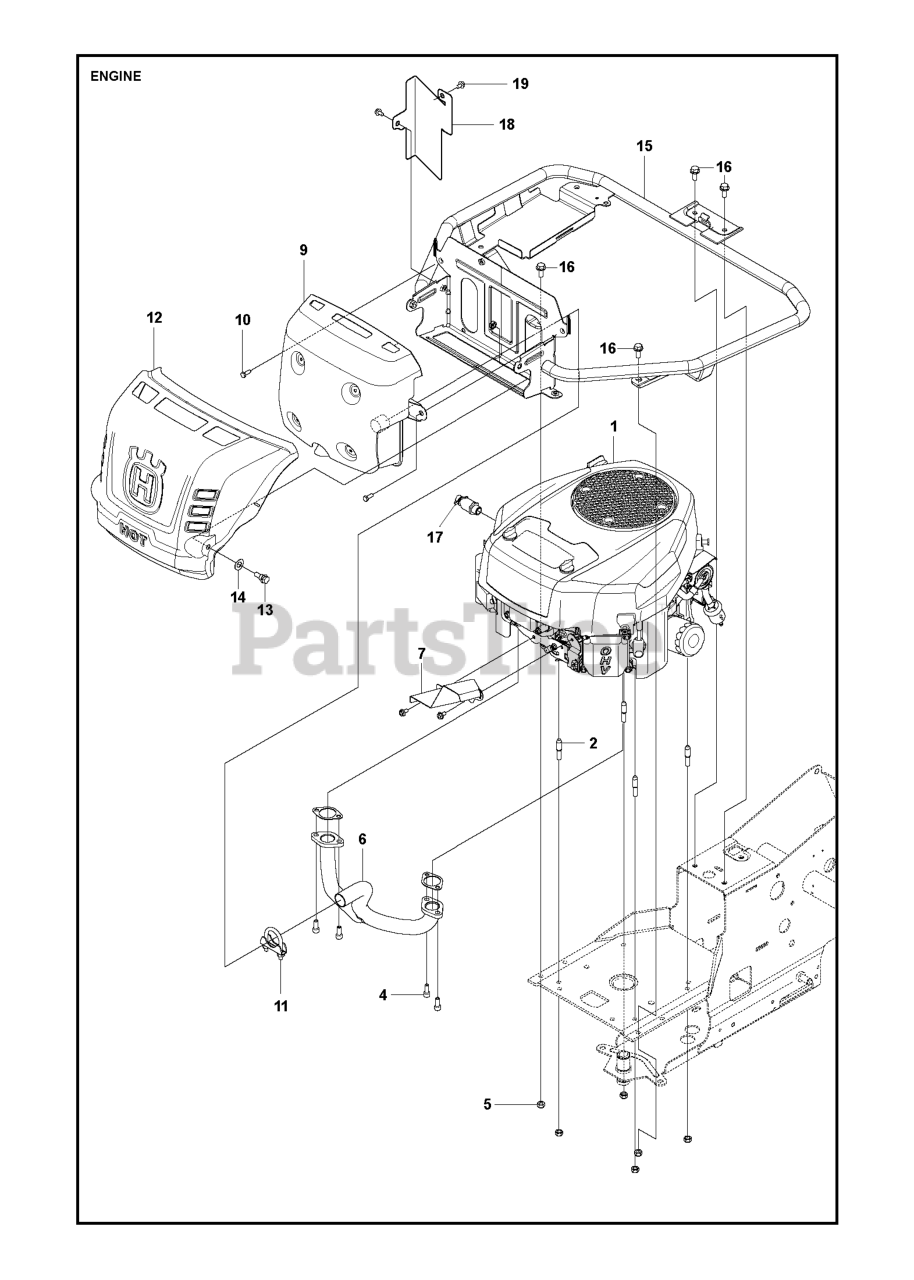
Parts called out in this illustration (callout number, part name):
2	STUD SCREW
5	LOCKNUT M8
11	CLAMP ASSY EXHAUST
12	HEAT SHIELD
14	SPRINGWASHER
17	VALUE.OIL.DRAIN
19	SCREW EHHFM
